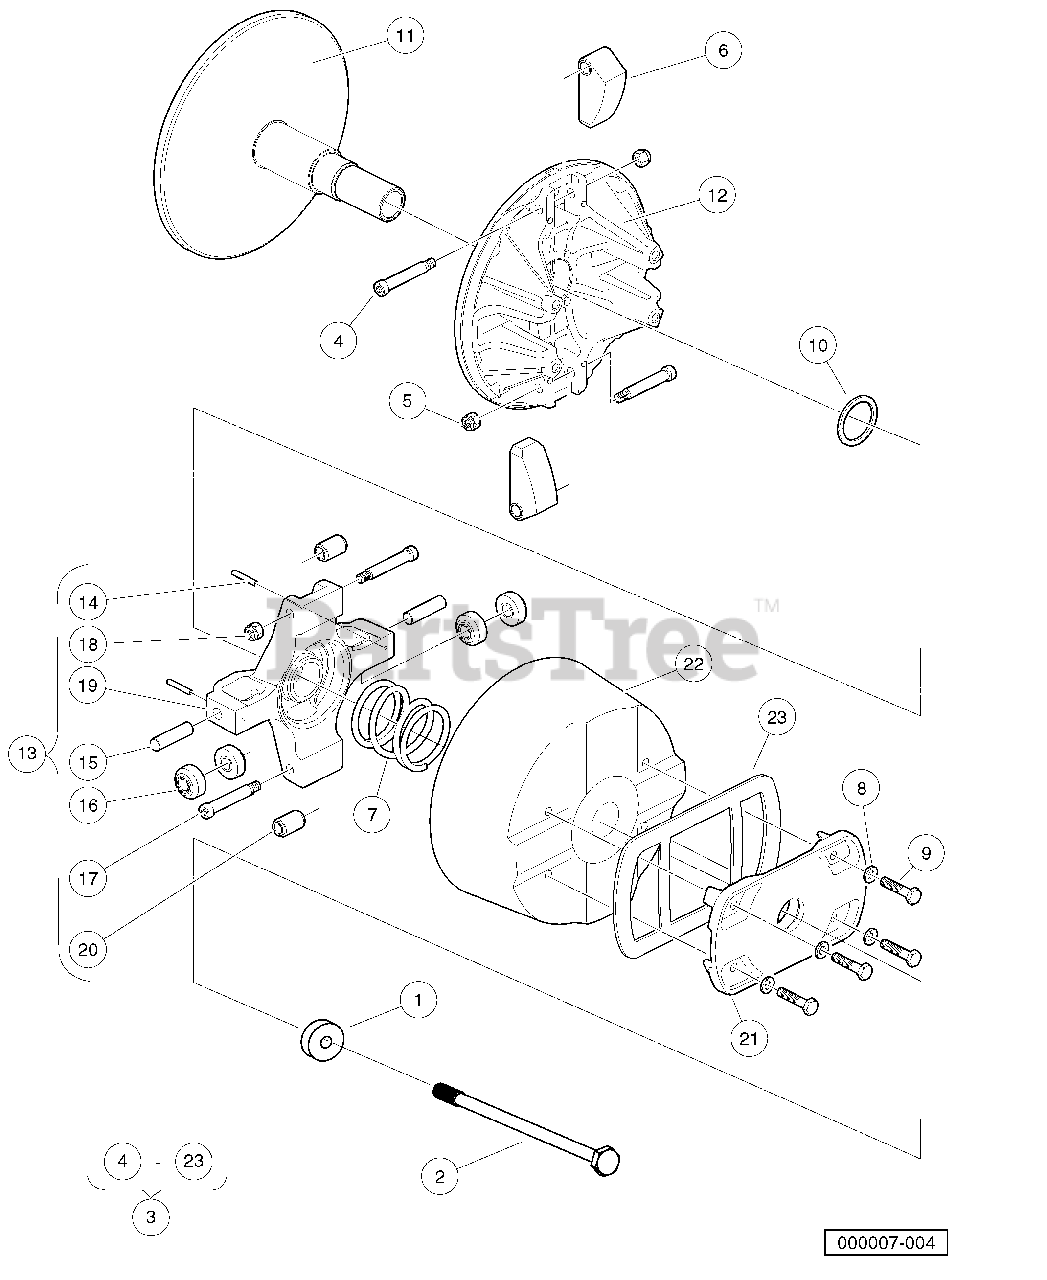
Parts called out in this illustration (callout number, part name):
1	Washer, Stepped
2	Bolt, M10 X 1.5 X 160
3	Clutch, 4x4, Diesel, W/cover
4	Screw, Shlder Hex, .312 X 1.75
5	Nut, Lock Hex, 1/14-20, Flexlc
6	Sub Assy, Wt Clutch, Diesel
7	Spring, Compression, Primary
8	Washer, Lock, H-Spring, 1/4
9	Screw, Cap, Hex Hd, 1/4 X 1.25
10	Shim, 1.63 X 1.33
11	Subassembly, Drive Clutch
12	Subassembly, Moveable, Drive Clutch
13	Subassembly, Spider Utility, Diesel
14	Pin, Spring Slotted,1.25 X 1.0
15	Pin, Dowel, .375 X 1.50
16	Roller, Torque, Diesel
17	Screw, Shlder Hex, .312 X 1.75
18	Nut, Lock Hex, 1/14-20, Flexlc
19	Spider, Drive Clutch
20	Sub Assy, Roller Weight
21	Cover, Drive Clutch
22	Cover, Clutch, 4x4
23	Gasket, Cover, Clutch, 4x4
